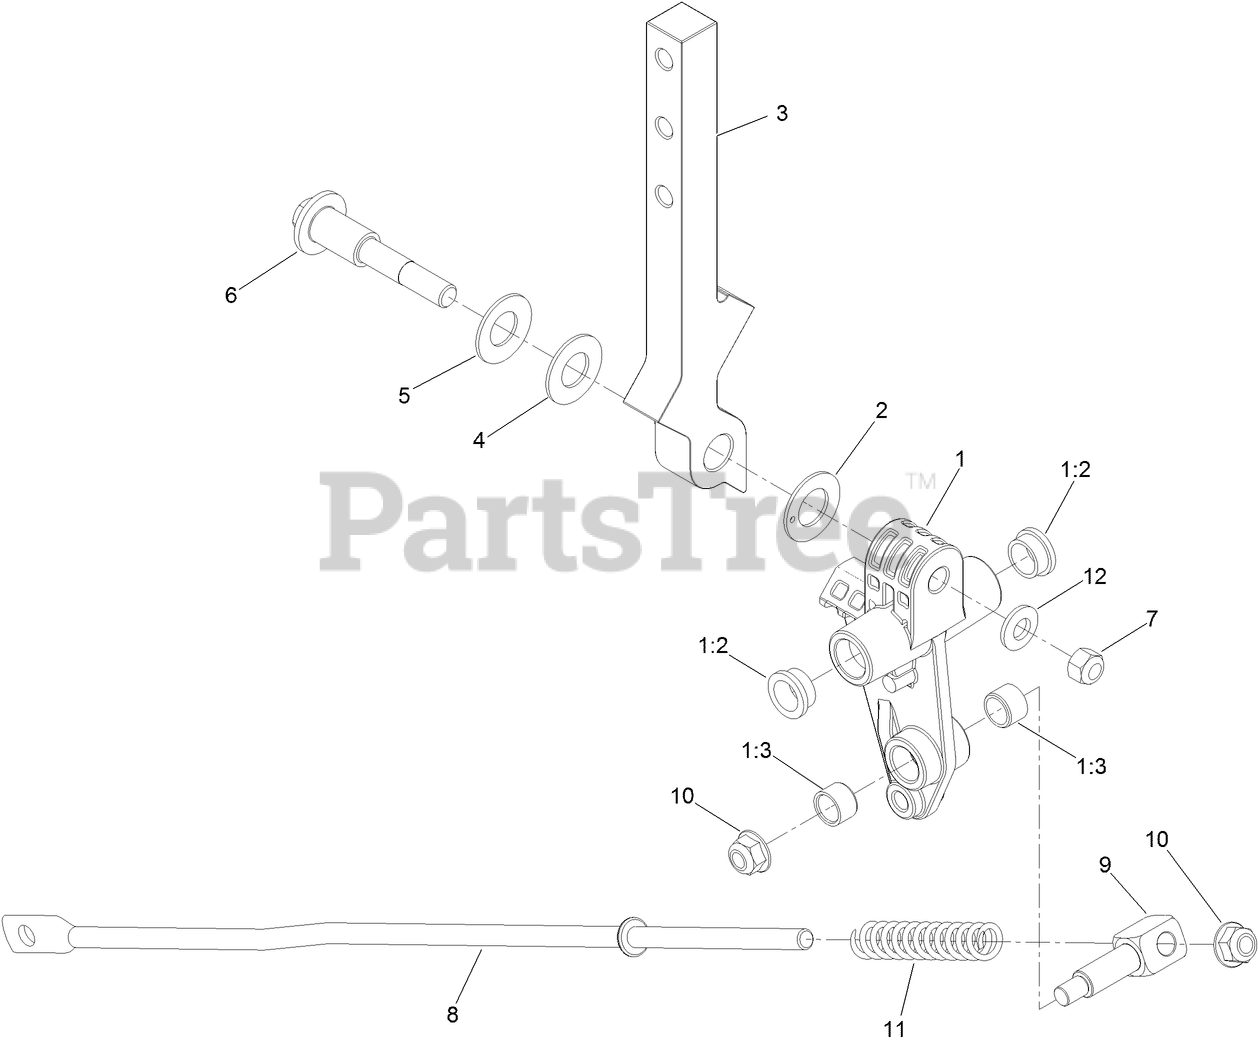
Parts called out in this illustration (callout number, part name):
1	CONTROL ARM ASM
1:2	BUSHING
1:3	BUSHING-SLEEVE
2	WASHER-FRICTION
3	ARM-CONTROL
4	WASHER
5	WASHER-BELLEVILLE
6	BOLT-PIVOT
7	NUT-LOCK, CONE
8	LINK-CONTROL
9	SWIVEL
10	NUT-HF, NI
11	SPRING-RETURN, NEUTRAL
12	WASHER-FLAT
